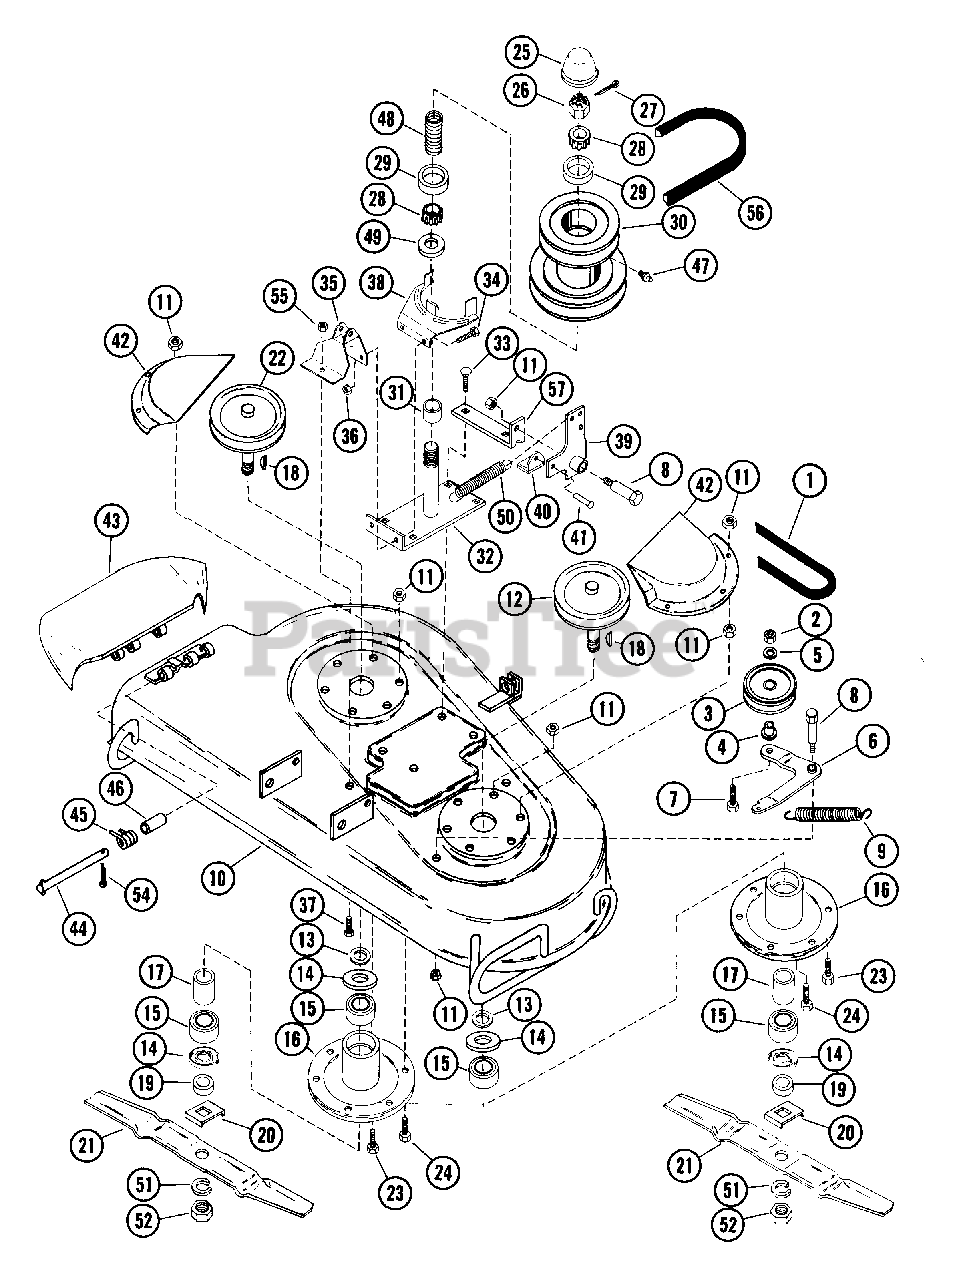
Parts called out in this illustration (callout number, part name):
1	V-BELT, 4L-RAW EDGE
2	NUT-LK-CTR .50-13
3	IDLER-FLAT 2.75X.62
4	BSHG-FLG .500X.625X.500X.750
5	WSHR-FL-STL .505X.880X.072 PL
7	BLT-HEX .50-13X1.25 PL GR2
8	SHOULDER BOLT
9	SG-TENS .091X.73X5.28 WLD 30
10	PAN ASSEMBLY
11	NUT-LK-CTR .375-16 GR A PL
13	WSHR-FL-STL .755X1.250X.125
14	BEARING SLINGER
15	BRG-BALL .751X1.78X.61
16	SPINDLE HOUSING
17	SPACER .753X1.000X1.140
18	KEY-WDRF .188X.75X.313 SAE 9
19	RETAINER HUB
20	BLADE TRAY
21	MOWER BLADE
22	SHEAVE
23	BLT-HEX .38-16X1.00 PL
24	BLT-HEX .38-16X.75 PL GR2
25	CAP, GREASE
26	NUT-JAM SL .75-20 PL
27	PIN-COTR .12 X 1.25 PL
28	BRG-CONE .750X.61
29	BRG-CUP 1.781X.475
30	SHEAVE ASSEMBLY-MOWER
31	SPACER .753X1.000X.625
33	BLT-RDHDSQNK .38-16X.75 SHT PL
34	BLT-SERHFWH .31-18X.75 PL
35	BRACKET
36	NUT-FLG. .312-18 PL
37	BLT-HEX .31-18X.50 PL GR2
41	RVT .25X.50 RH ST
43	CHUTE DEFLECTOR UNIT
44	CLEVIS PIN
45	SG-TORS .095X.50X 1.0
46	BSHG-SLV .334 X .502 X 1.437
47	SPIN DRIVE ZERK FITTING
48	SG-COMP .091X.950X2.062
49	SEAL .750X1.690X.153
50	SG-TENS .072X.50X8.0 WLD 25
51	WSHR-LK .750X.188 MED PL
52	NUT-JAM .75-10 PL
54	PIN-COTR .09X.75 PL
55	NUT-LK .312-18 GR A PL
56	V-BELT, 5L-RAW EDGE
57	BRACKET
